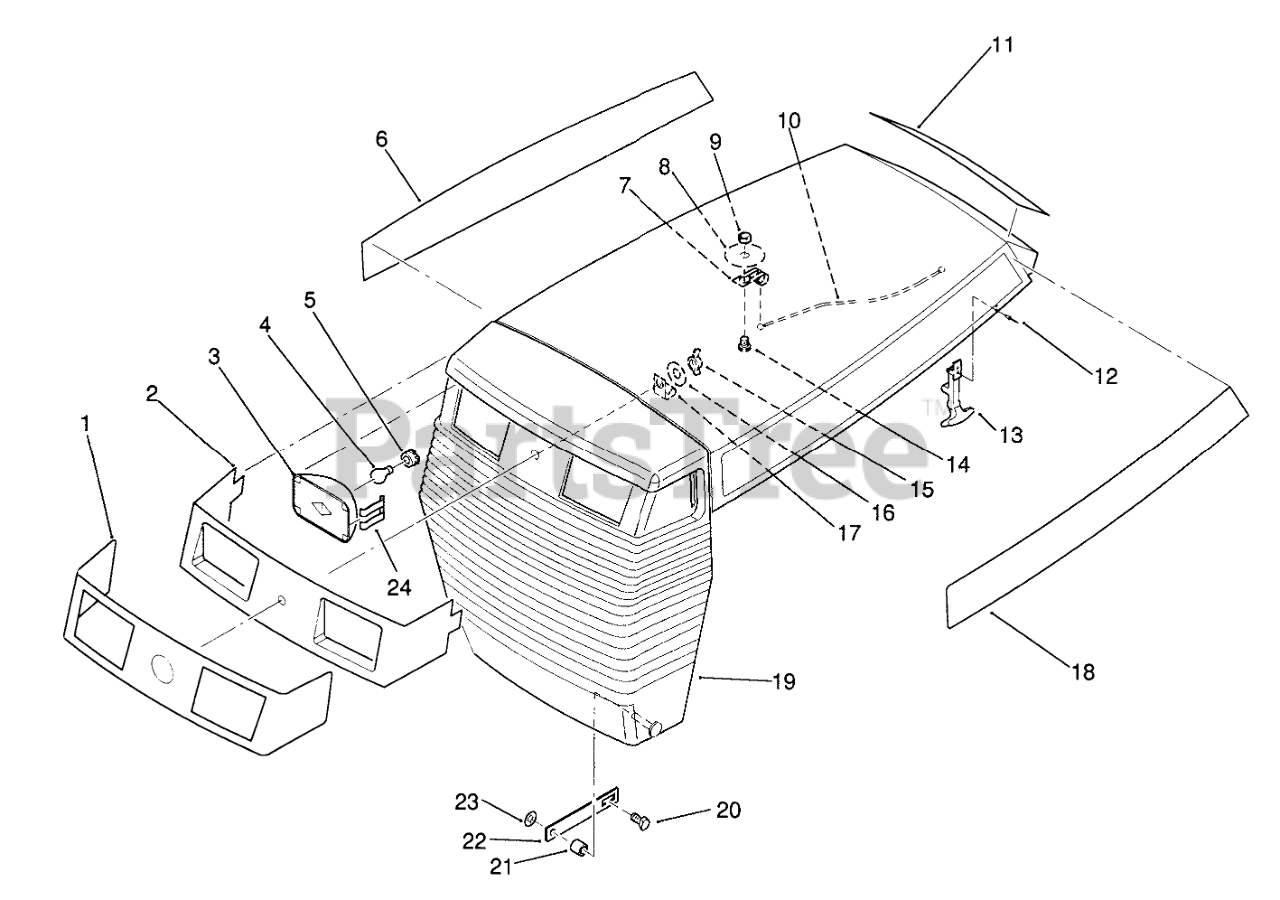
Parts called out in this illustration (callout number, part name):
1	DECAL-FRONT HOOD
2	LIGHT-BAR BLACK
3	LIGHT POD
4	BULB
5	SOCKET-HEADLIGHT
6	DECAL-HOOD R.H. 244H
7	CLEVIS
8	WASHER-BACKING
9	Nut
10	CABLE-ASS'Y
11	Decal-Hood Rear
12	RIVET-POP
13	HANDLE ASM
14	SCREW
15	WING NUT
16	WASHER
17	J-CLIP
18	DECAL-HOOD L.H. 244H
19	Hood W.A.
20	Screw
21	SPACER
22	STRAP R
23	PUSH-NUT 5/16
24	RETAINER
